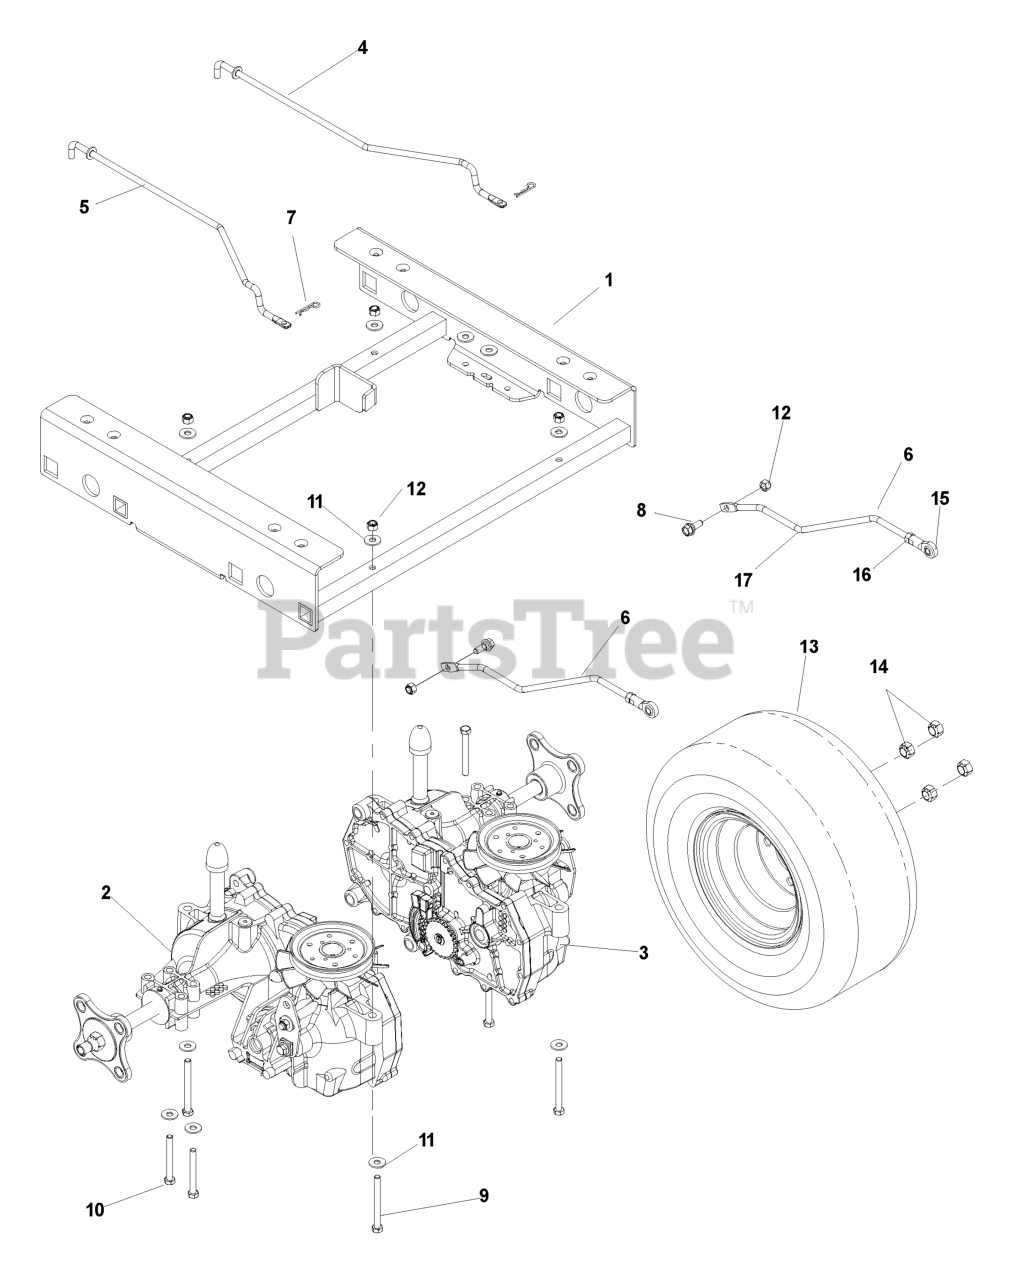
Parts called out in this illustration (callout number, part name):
1	SUB FRAME PAINTED
2	HG_EZT RIGHT
3	HG_EZT LEFT
4	BYPASS LINKAGE, LEFT
5	BYPASS LINKAGE, RIGHT
6	MOTION CONTROL ROD ASM
7	HAIRPIN #2
8	BOLT, SHOULDER
9	HCS 5/16-18 X 3 1/4
10	HCS 5/16C X 2-3/4
11	WASHER 5/16 FLAT
12	NUT 5/16 NYLOC
13	TIRE/WHEEL.ASSEM.18X7.5-8.ZTR
13	WHEEL ASM.18X8.5-8.KENDA.
13	VALVE STEM TR-412
14	LUG NUT 1/2F
15	BALL JOINT, RIGHT HANDED
17	MOTION ROD
